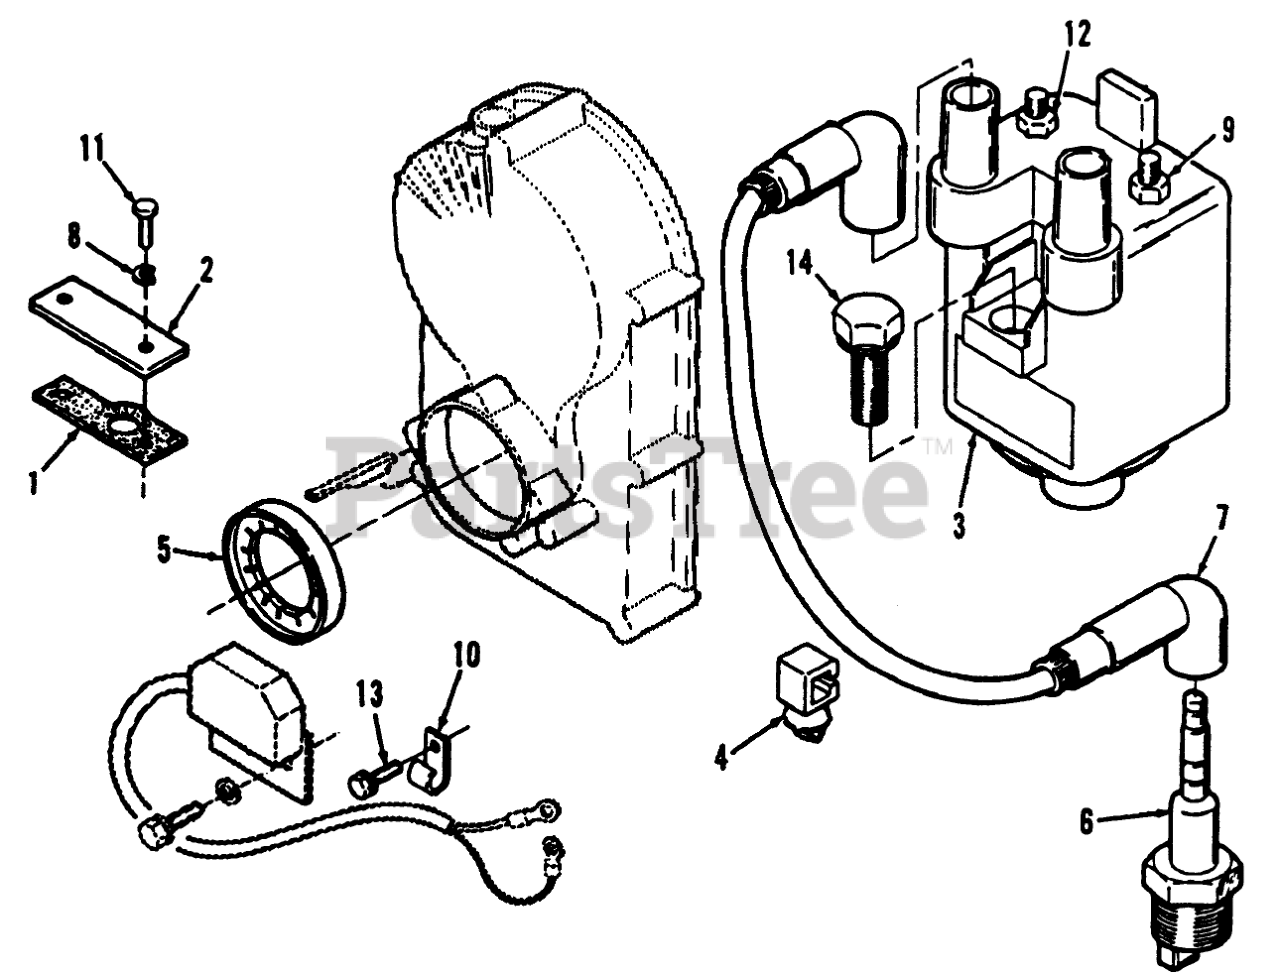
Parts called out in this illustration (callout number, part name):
1	Gasket-Plate
2	Plate
3	Coil-Battery Ignition (Includes Nuts)
4	Clip
5	Rotor
6	Plug-Spark
7	Wire-Plug
8	WASHER-FLAT
9	Nut
10	Clip
11	SCREW - CAP HEX HEAD
12	Nut
13	Bolt
14	Bolt
